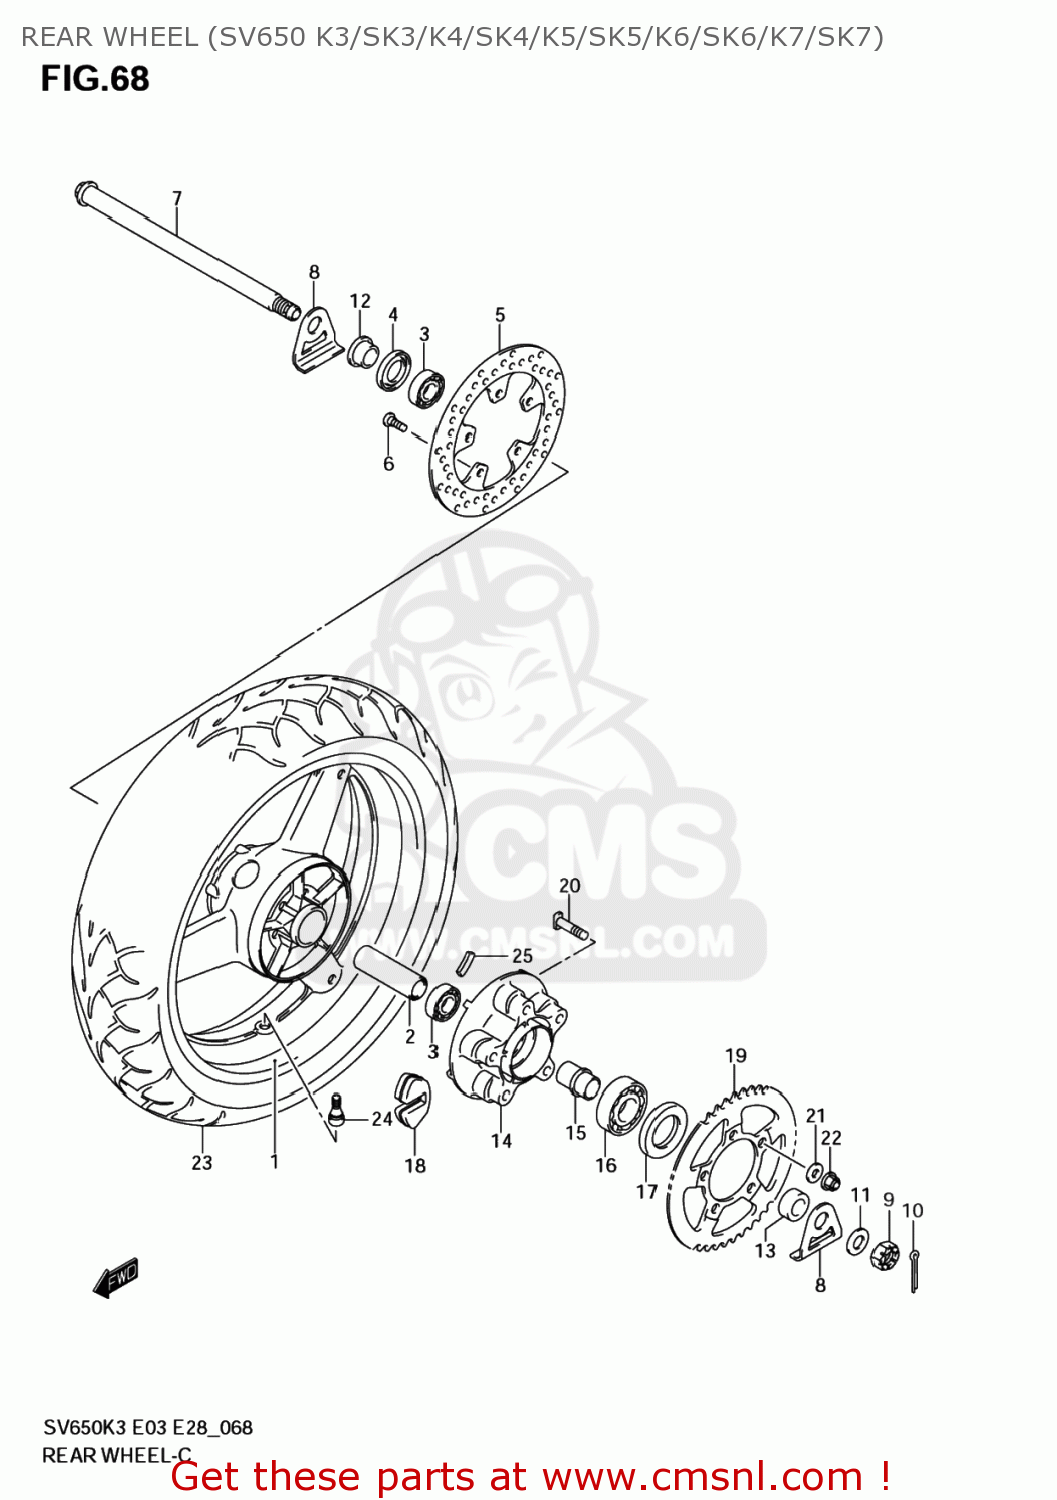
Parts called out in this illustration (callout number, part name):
1	WHEEL,REAR,17X
2	SPACER(20.5X28X88)
3	BEARING(20X47X14)
4	SEAL,OIL(28X47X7)
5	DISC,RR BRAKE
6	BOLT(8X33)
7	AXLE,RR
8	WASHER,CHAIN ADJUSTER
9	NUT
10	PIN, COTTER
11	WASHER(18.5X28X2.6)
12	SPACER,RR AXLE,R
13	SPACER,RR AXLE,L
14	DRUM,RR SPROCKET MOUNTING
15	RETAINER,RR HUB BEARING
16	BEARING(25X62X17)
17	SEAL,OIL(35X62X8)
18	ABSORBER,RR HUB SHOCK
19	SPROCKET,RR(NT:45-525)
20	BOLT(10X47)
21	WASHER (10.5X22X2.3)
22	NUT
23	TIRE,RR(160/60 ZR17M/C 69W)
24	VALVE ASSY,WHEEL RIM(TR412)
25	BALANCER,WHEEL(10G)
